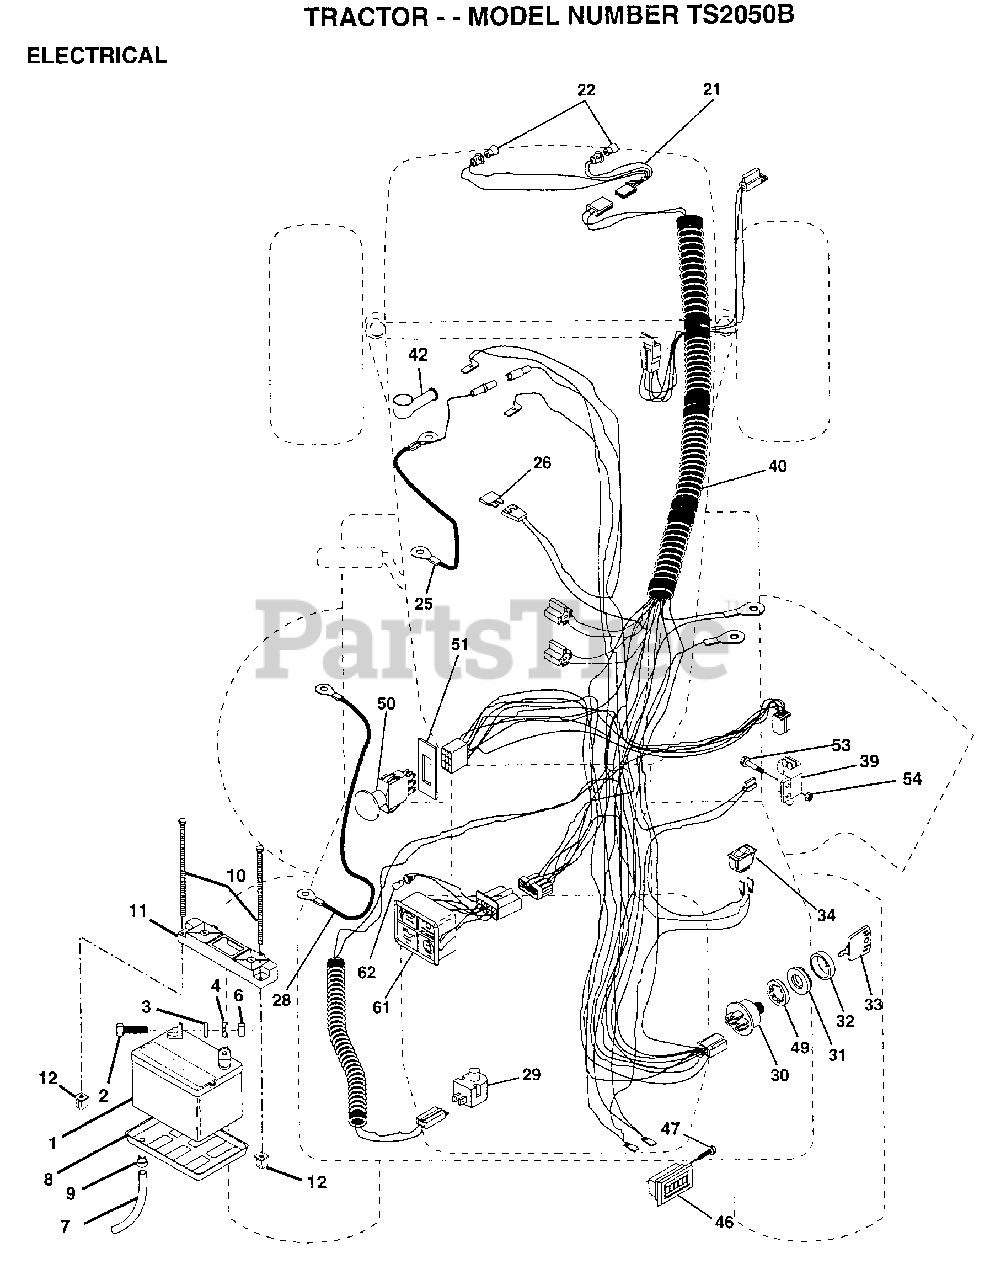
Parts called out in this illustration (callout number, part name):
2	BOLT LT
3	LOCKWASHER
4	WASHER
5	"CAP,BATTERY "
7	"DRAIN TU T, BATT"
8	"TRAY T, BATTERY"
9	HOSE CLAMP T
21	"HARNESS,LIGHT SOC"
22	HEADLAMP BULB
25	MANUAL.OP.GEN.ENG
26	FUSE HYT
28	CABLE.BATRY.4GA.
29	SWITCH SEAT
30	SWITCH T
31	NUT IGNITION
33	KEY
34	SWITCH LT
39	SWITCH INTERLOCKT
40	"HARNESS,IGNITION"
46	HOUR METER T
47	SCREW
49	LOCKWASHER
51	RING RETAIN PTO
53	SCREW
54	"NUT,KEPS"
61	LIGHT.PKG.ASM.
62	BULB LIGHT T
